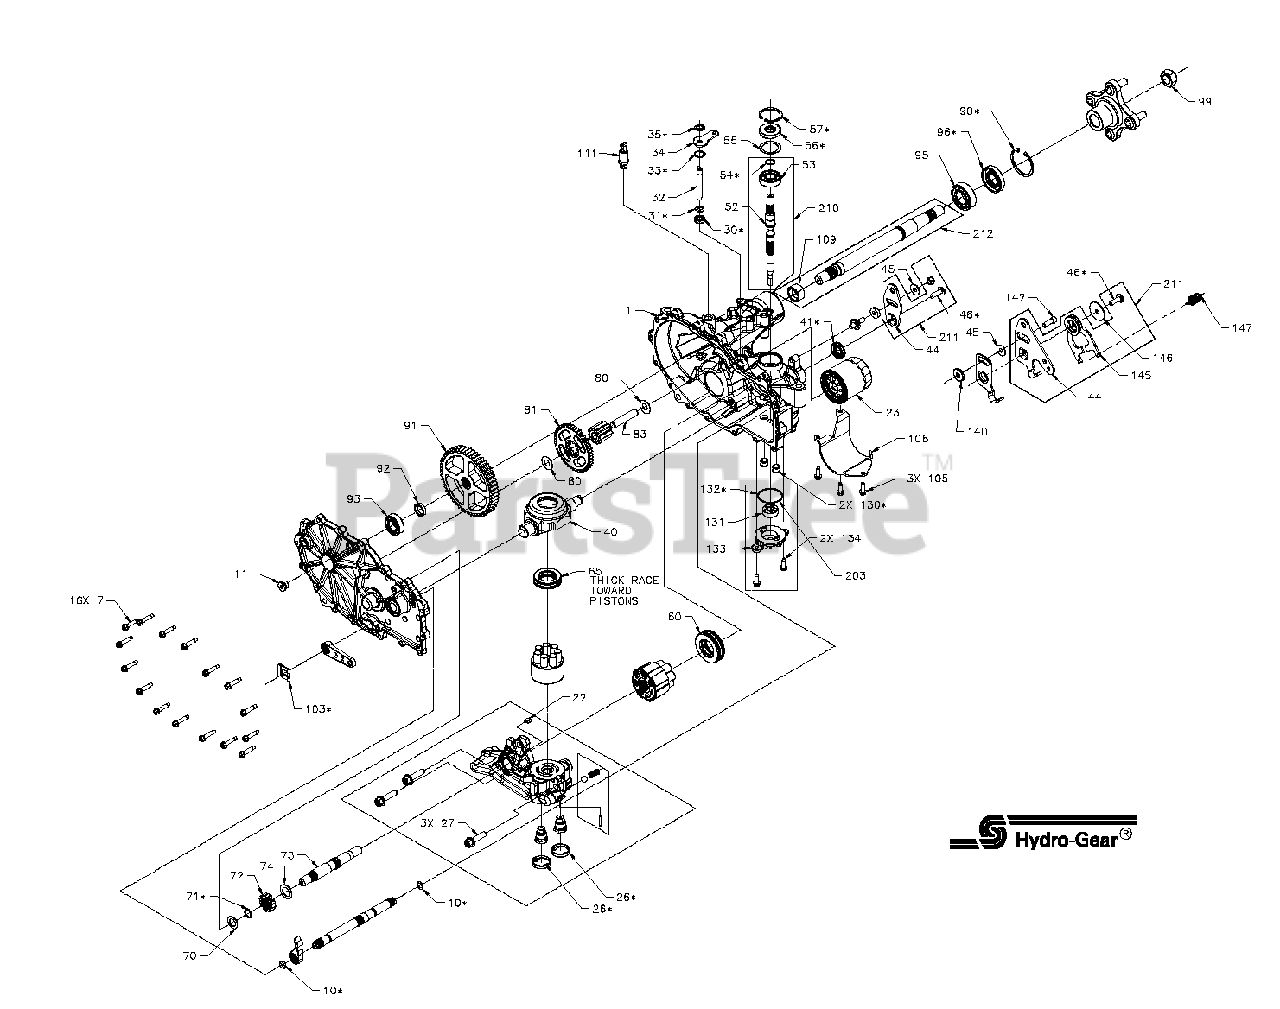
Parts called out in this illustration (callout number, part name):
7	HFHCS 1/4-20 x 1.25
11	Plug, 9/16-18 (Metal)
22	Plate, Bypass
30	Seal, Lip .375 x .75 x .25
31	Ring, Retention .375 External
33	Ring, Retention .750 Internal
35	Ring, Retention .375 Ext
40	Trunnion, Swashplate
45	Washer, .34 x .88 x .06
46	TWHCS 5/16-24 x 1.00
53	Bearing, Ball 17 x 40 x 12 Open 6203
55	Washer, 1.23 x 1.56 x .04
56	Seal, Lip 17 x 40 x 7
57	Ring, Ret 1.59 Int
65	Bearing, Thrust Ball 30 x 52 x 13
70	Washer, .63 x 1.0 x .05
71	Ring, Retaining .625
74	Washer, .72 x 1.16 x .04
80	Washer, .5 x 1.0 x .03
83	Jack Shaft
90	Ring, Ret 2.06 Int
95	Bearing, Ball 1.0 x 52 x 15 Open 6205M
96	Seal, Lip 25 x 52 x 10 TC (Gray)
99	Nut, Hex Lock 3/4-16
105	HFHCS 1/4-20 x .75
131	Assembly, Gerotor Tang x 1.15 x .39
134	HFHCS 1/4-20 x .75
142	SHCS 5/16-24 x 1 Patch
146	Washer, .343 x 1.5 x .062
NS	Sealant
